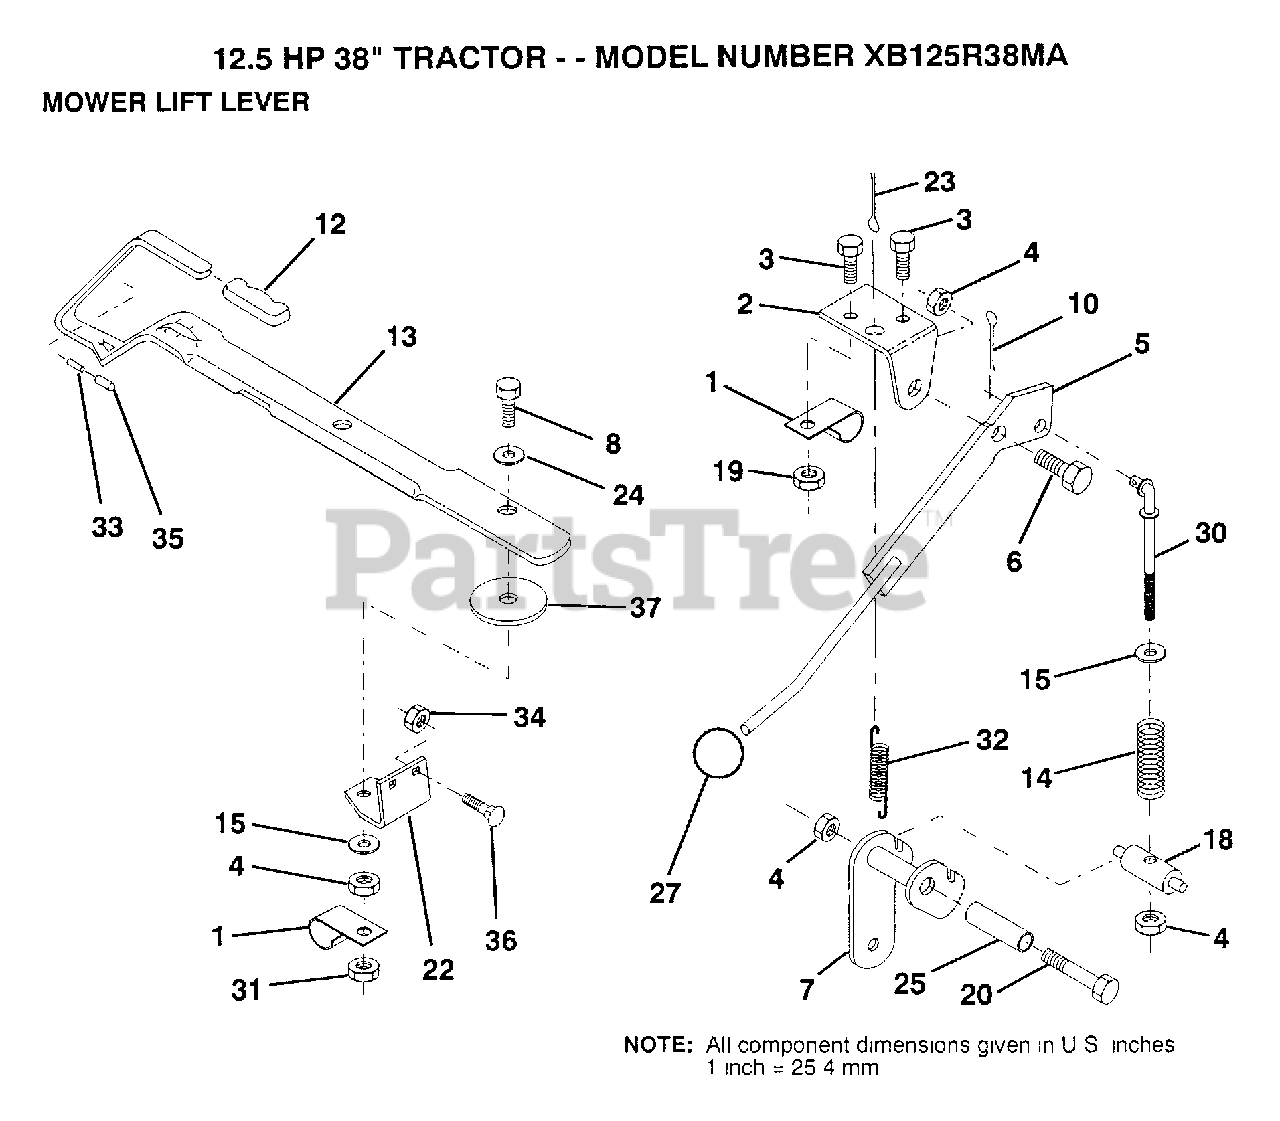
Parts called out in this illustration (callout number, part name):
1	"CLIP,INSULATOR"
2	BRKT CLUTCH
3	BOLT
5	CLUTCH LEVER AS
6	"BOLT, SHOULDER LT"
7	MWR CLUT ARM ASM
8	BOLT
10	COTTER PIN
12	LIFT LEVER HANDLE
14	COMP CLUTCH SPRNG
15	WASHER HYT
18	TRUNNION
20	BOLT
22	LIFT LEVER BRKT
24	WASHER
25	TUBE SPACER
27	KNOB
30	ROD TENSION CLUTC
31	LOCKNUT
32	SPRING EXT
35	VINYL CAP RED
36	BOLT
37	WASHER T
